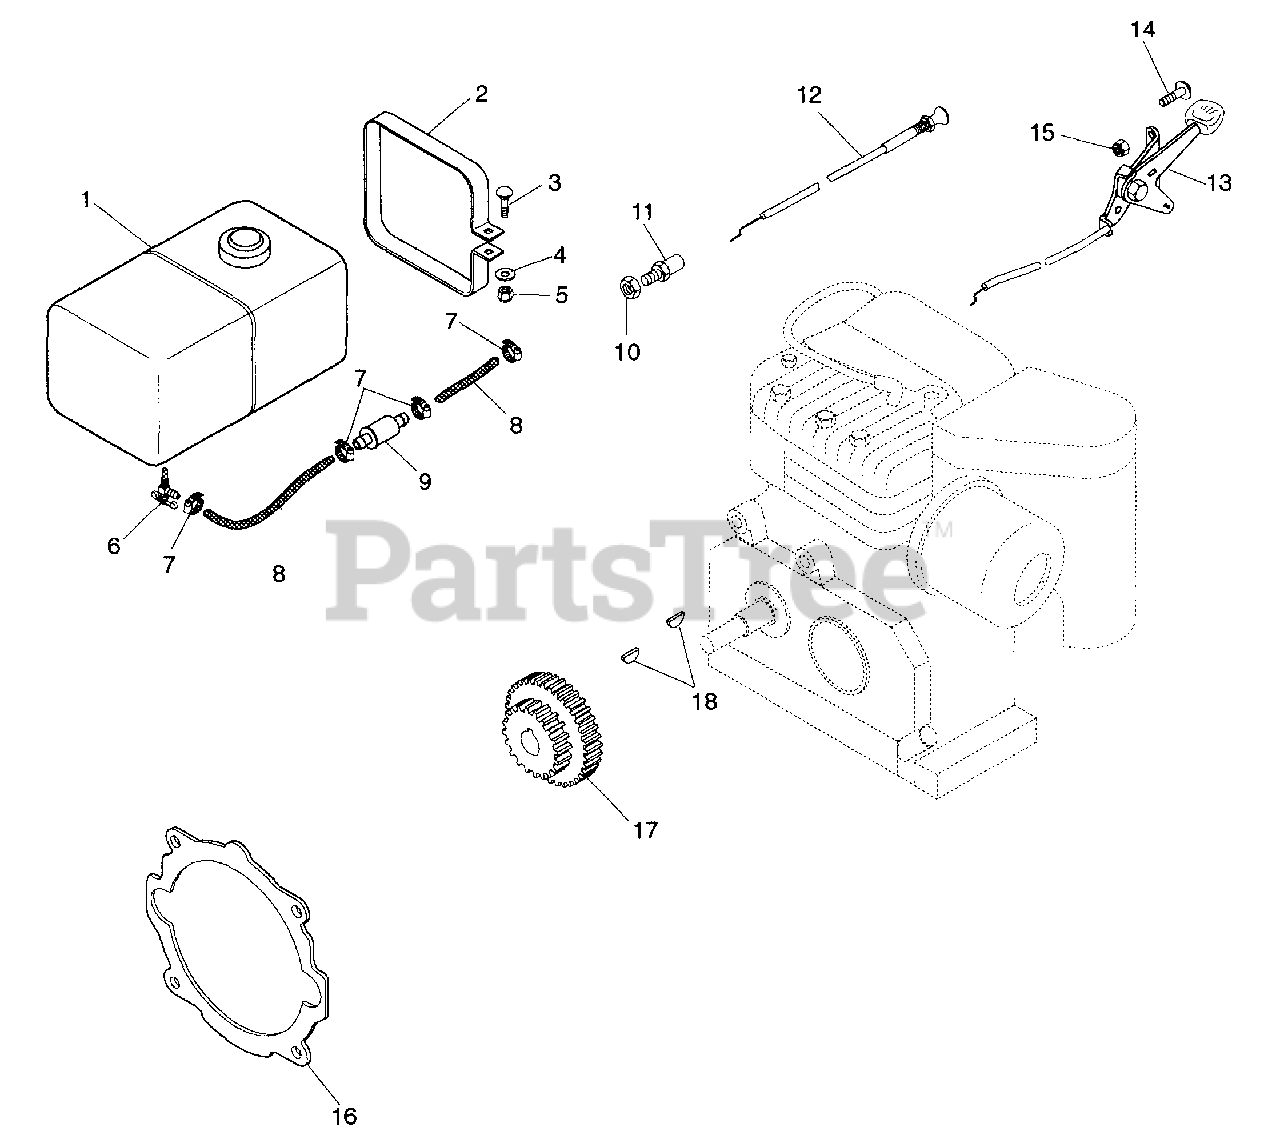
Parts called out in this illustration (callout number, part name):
1	Tank, Fuel w/Cap,
2	Strap, Fuel Tank
3	Bolt-Round Head Square Neck .25-20 x 1.75
4	Washer-Flat-Steel .312 x .734 x .065
5	Nut-Lock-Nylon .250-20
6	Valve and Strainer
7	Hose Clamp
8	Gas Line - Bulk
9	Filter, Fuel
10	Nut-Hex .250-20
11	Adapter, Conduit
12	Lever, Choke Control
13	Lever, Throttle Control
14	Screw-Machine 10-24 x .50
15	Nut-Lock 10-24
16	Gasket, Chassis to Adapter
17	Gear, 10/12 DP 21/30 Teeth
18	Key, Woodruff.16 x .63
